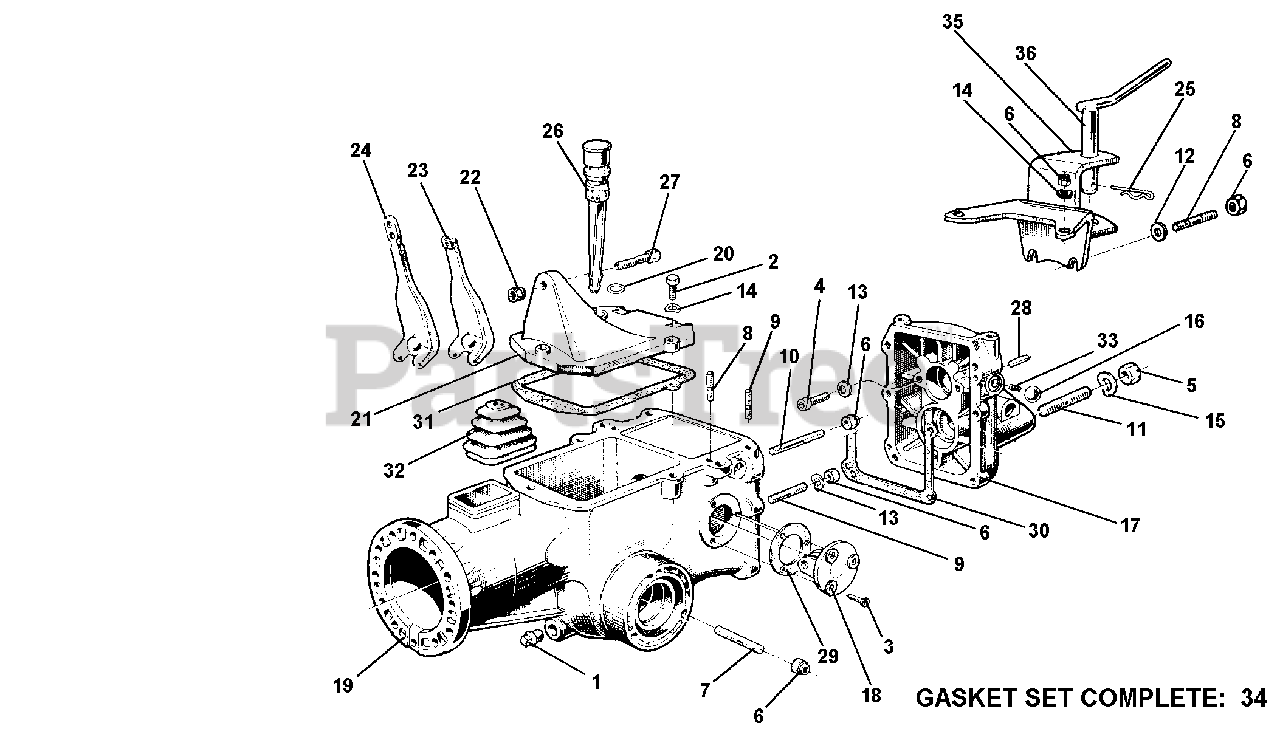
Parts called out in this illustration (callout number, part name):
1	PLUG 1/4 GAS
2	SCREW TE M8 X 25
3	SCREW M6 X 16
4	SCREW TCCEI M8 X 12
5	NUT M12 X 1.25 UNI 5587 6S
6	NUT, SELF LOCKING M8
7	STUD M8 X 46 X 20 X 12
8	STUD M8 X 38 X 14 X 20
9	STUD M8 X 46 X 16 X 16
10	STUD M8 X 58 X 16 X 16
11	ST.56M12X1.25X26XM12X22 8G
12	WASHER, FLAT 8.4
13	SUPER WASHER 8 DIN 6796
14	WASHER, LOCK 8.4
15	WASHER, LOCK 13
16	BALL 15/32 RIV RB-11.906
17	HOUSING COVER
18	FLANGE, REVERSE SPEED
19	HOUSING BODY
20	RUBBER RING
22	STOP RING NUT
23	CLUTCH LEVER
24	CLUTCH LEVER
26	CAP, WITH MEASURING ROD
27	SCREW, ADJUSTING M8
28	PARALLEL PIN D 6 X 20
30	GASKET COVER
31	GASKET COVER
33	P.T.O. SPRING
34	GASKET SET COMPLETE 715-725
35	TOW COUPLING
